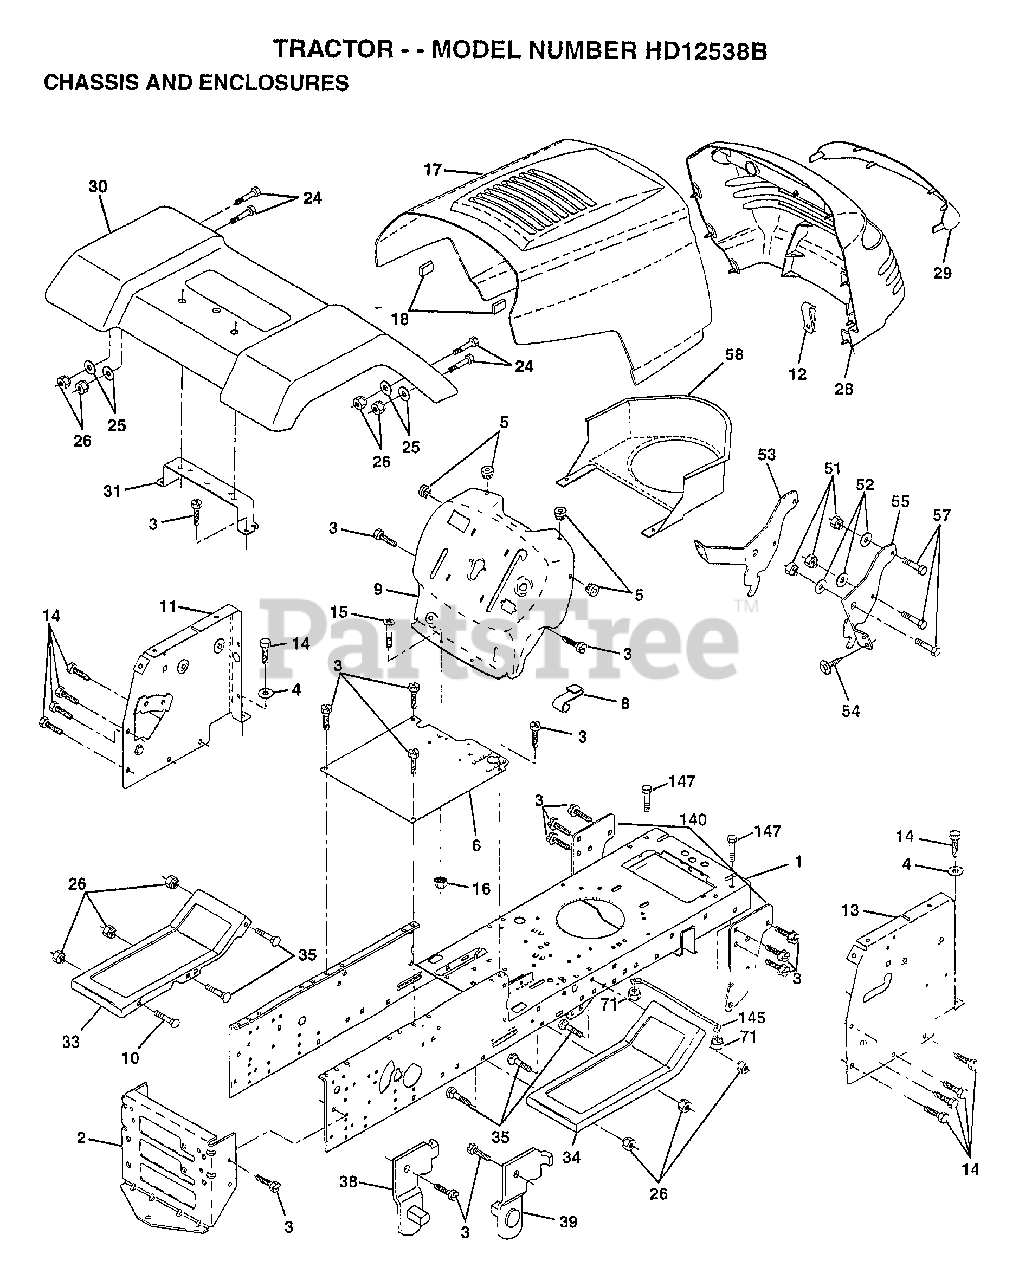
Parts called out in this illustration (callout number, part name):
1	CHASSIS ASM
3	SCREW
4	WASHER
5	BUMPER-HOOD/DASH
6	SADDLE-SILKSCREEN
8	CLIP.RETAINER
9	DASH.SILKSCREENED
11	"PANEL-DASH,LH"
12	CLIP.TINNERMAN
14	SCREW LT
15	SCREW
24	BOLT
25	WASHER
26	NUT
28	GRILLE
29	LENS QUADRA
31	BRKT FENDER
33	FOOTREST.LH.PERF.
34	FOOTREST.RH.PERF.
35	BOLT
38	BRACKET ASM LH
39	BRACKET ASM RH
51	NUT
52	WASHER
53	BRACKET.GRILLE.LH
55	BRACKET.GRILLE.RH
140	BRKT SUSPENSION
145	"ROD POVOT,CHASSIS"
147	BOLT LT
